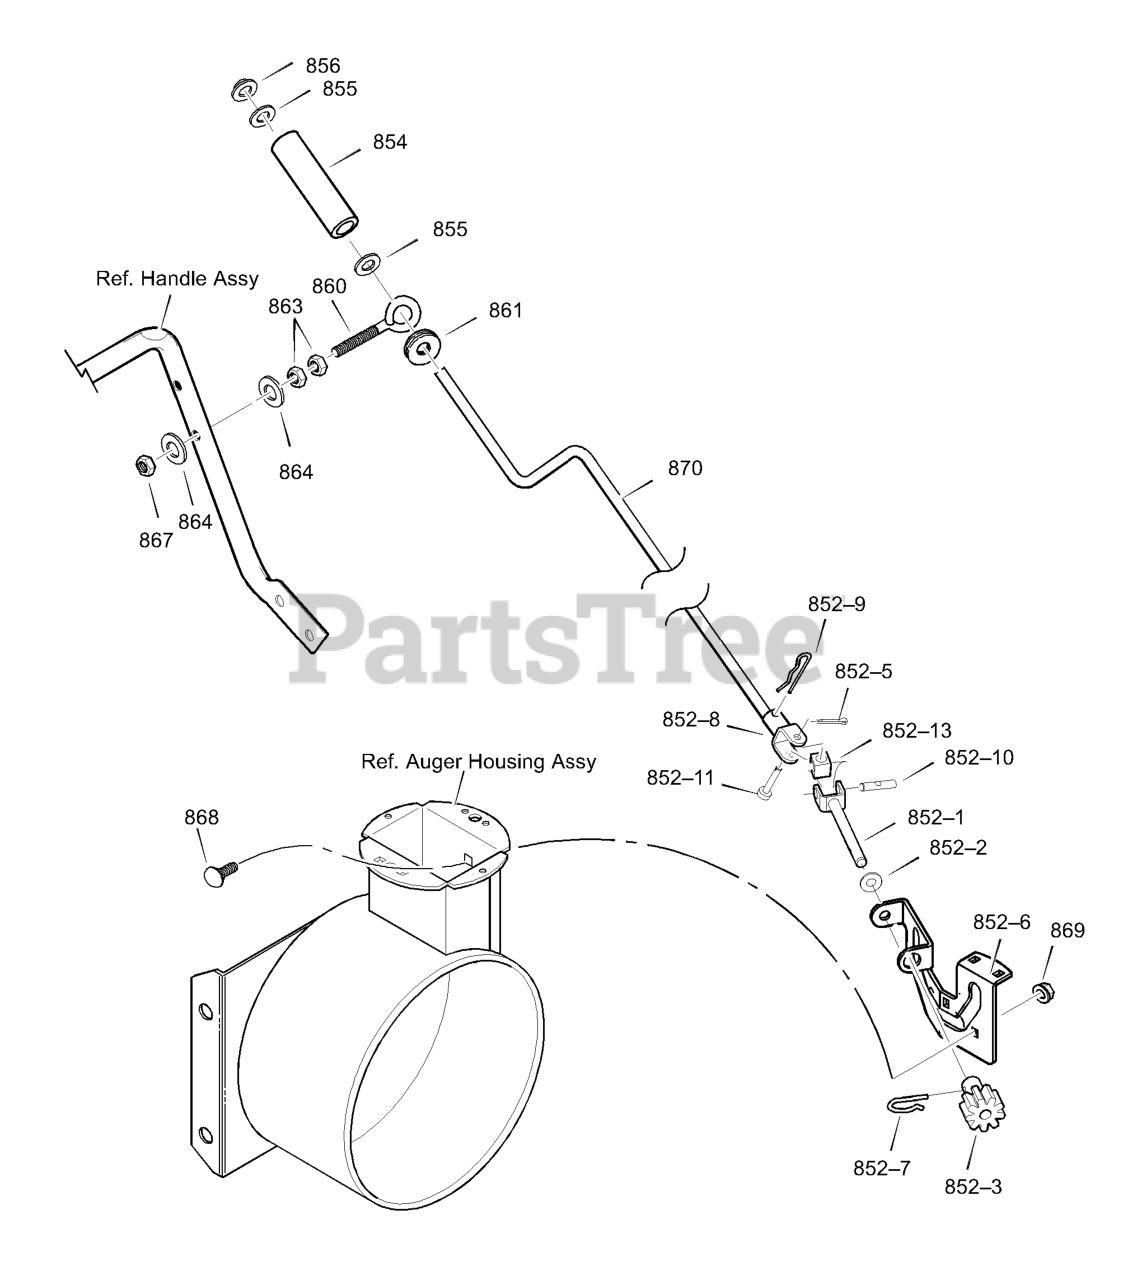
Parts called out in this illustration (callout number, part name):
852-1	ASSEMBLY, YOKE & ROD
852-2	WASHER, CURVED SPRING
852-3	GEAR, CHUTE ROTATION 9T
852-5	PIN, COTTER
852-6	BRACKET, GEAR MOUNT
852-7	PIN, HAIR
852-8	ASSEMBLY, YOKE ADAPTER YZ
852-9	PIN, HAIR
852-10	PIN, UNIVERSAL JOINT
852-11	PIN, CLEVIS
852-13	HOUSING, UNIVERSAL
854	KNOB, SLEEVE
855	FLATWASHER
856	NUT, PUSH ON 3/8"
860	EYE BOLT 3/8-16X6.00
861	GROMMET, EYE BOLT
863	NUT, 3/8-16 HEXJAM
864	FLATWASHER .406X.81X.066
867	NUT, 3/8-16 HEXNYL
868	BOLT, CARRIAGE 1/4-20 X 1.00
869	NUT
870	CRANK, ASSY CHUTE
